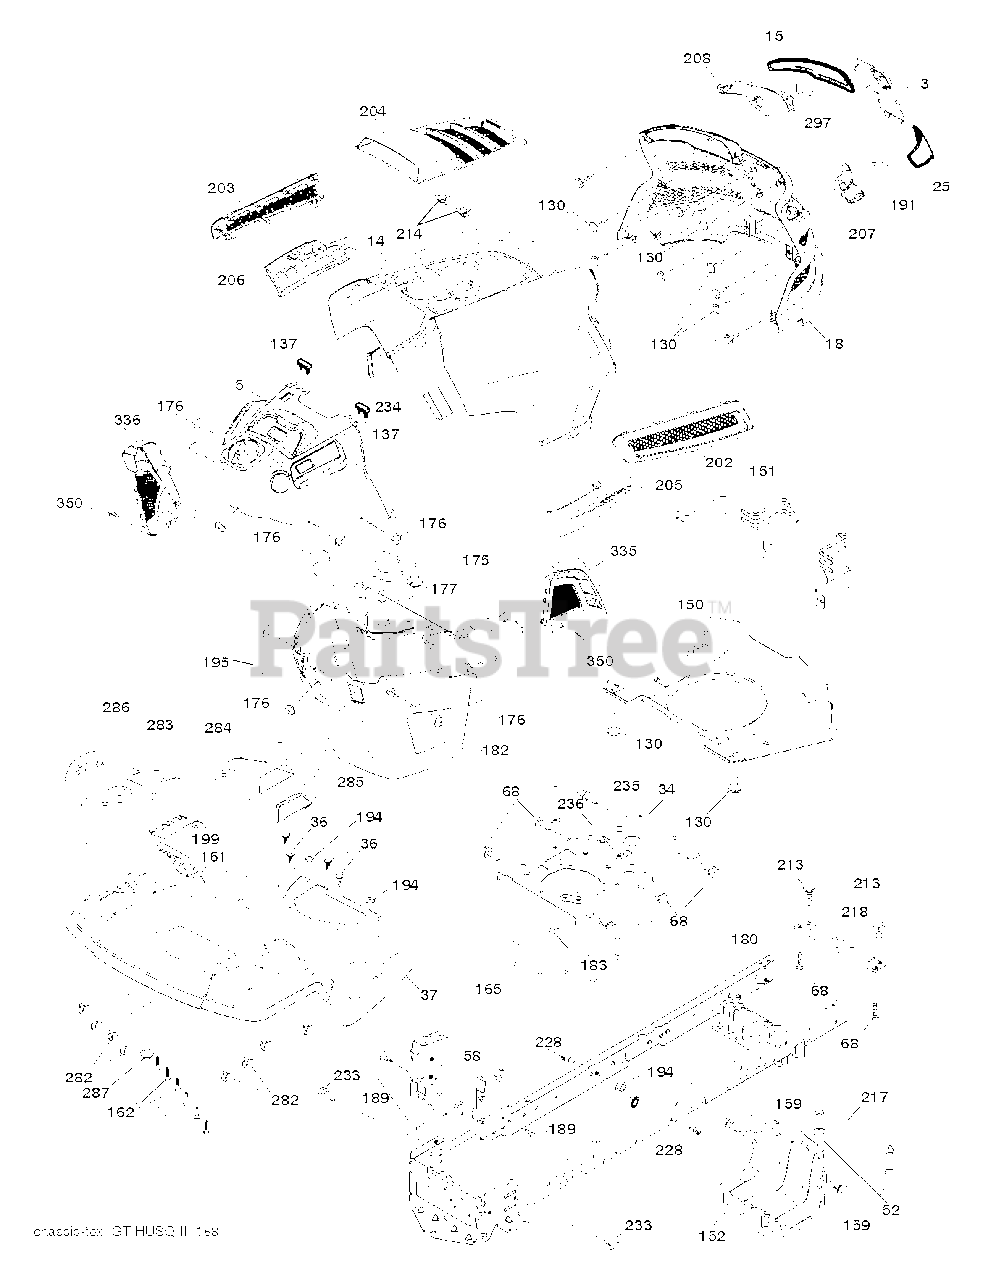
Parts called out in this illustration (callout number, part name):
3	APPLIQUE.SUBASM.GT.HUSQ.II
5	UPPER.ASSY.GT2.498.GRY
14	HOOD.ASM.HUSQVARNA.GT.TEX.ORAN
15	LENS.HEADLIGHT.LH.GTII.2011
18	GRILLE.SUBSTRATE.2011.
25	LENS.HEADLIGHT.RH.GTII.2011
34	PLATE.ENGINE.WELDED.CHASSIS
36	SCREW 5/16"
37	FENDER.TLT.FS.W/CPH/FW/RSF.668
52	LOCKNUT
58	DRAWBAR UPPER 2PC SMALL FENDER
68	SCREW LT
130	SCREW.#10 X 0.750.BOS
137	BUMPER DASH
150	AIR.DUCT.GTV.BLACK
151	BRACKET.PIVOT.HOOD.GT.HUSQ.II
152	SHIELD.BROWNING.PNT.GT.V2
159	SCREW, 3/8-16X3/4
161	WINDOW.FUEL.LT.HUSQ.TEX.498
162	SCREW.HI-LO.CONSOLE
165	SUPPORT.TANK.REAR.W/TEX
175	PLATE.CROSSMEMBER.HUSQ
176	SCREW.#10-24X5/8.RN.QU
177	BUSHING STEERING
180	CHASS.WLDMNT.TL.12GA/2P.48/54
182	DASH.LOWER.COMMON.12V.ADAPTOR
183	BOLT.5/16-18X1-1/4 FULL THD
189	SCREW, 3/8-16X3/4
191	INSERT.REFLECTIVE.RH.HUSQ.GTII
194	NUT LOCK HEX FLANGE 5/16-18
195	PLUG.HOLE.DASH.LOWER.12V.BLK
199	PLATE.DECK.LIFT.HUSQ.LT
202	VENT.SIDE.RH.GT.HUSQ.II.
203	VENT.SIDE.LH.GT.HUSQ.II.498
204	VENT.TOP.HUSQ.GT2
205	SIDE.TRIM.RH.GT.HUSQ.II
206	SIDE.TRIM.LH.GT.HUSQ.II.GRAY
207	BEZEL LIGHT.RH.GT.II.MYLAR
208	BEZEL LIGHT.LH.GT.II.MYLAR
213	BOLT
214	CLIP.RETAINER.TINNER.
217	ROD.PIVOT.HOOD
218	X-PIECE.HOOD.STOP.NON/
228	STUD.FASTNER.W/ANTI-ROTATE
233	BOLT.SHOULDER
234	BUMPER.HOOD.TEX.HUSQVARNA
235	SPACER FENDER
236	NUT.CENTERLOCK.5/16-
282	CLIP.RETAINER.CONSOLE.LT.HUSQ
283	CONSOLE.DECK.LIFT.R.SDFL.HUSQ
284	CONCOLE.CNTRL.PDL.HUSQ.LT.498
285	CONSOLE INSERT RH
286	CONSOLE.INSRT.LH.HUSQ.LT.BLACK
287	SCREW 1/4X20
297	INSERT.REFLECTIVE.LH.HUSQ.GTII
335	COVER.LOWER.DASH.RH.BLACK
336	COVER-LH.LOWER.DASH.GT2.BLACK
350	CLIP.X-MAS.TREE
